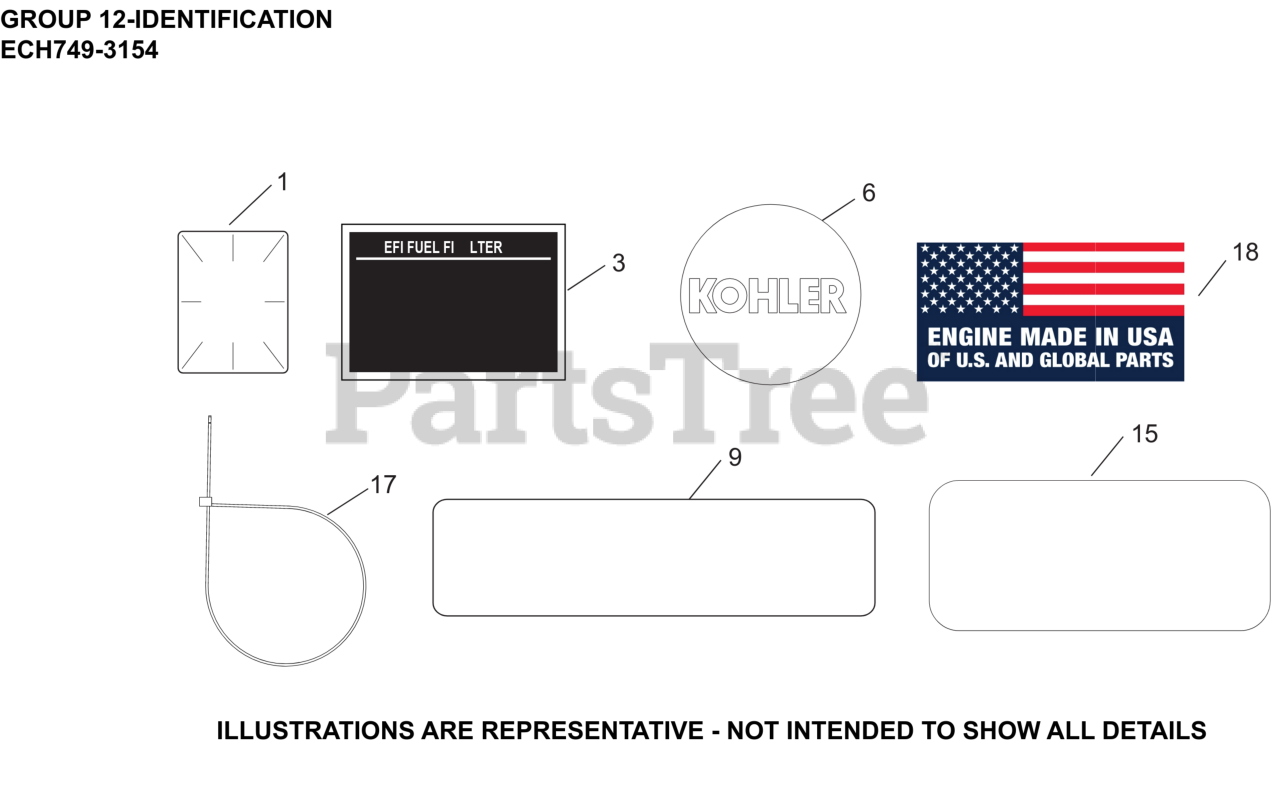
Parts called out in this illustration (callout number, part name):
1	LABEL, CLEAR LAMINATION
3	LABEL, EFI FUEL FILTER
6	LABEL, GRASS SCREEN
9	DECAL LPAC, 26.5 HP/747cc/ECV-ECH749
15	DECAL, ANTI-ICING
18	DECAL, USA
